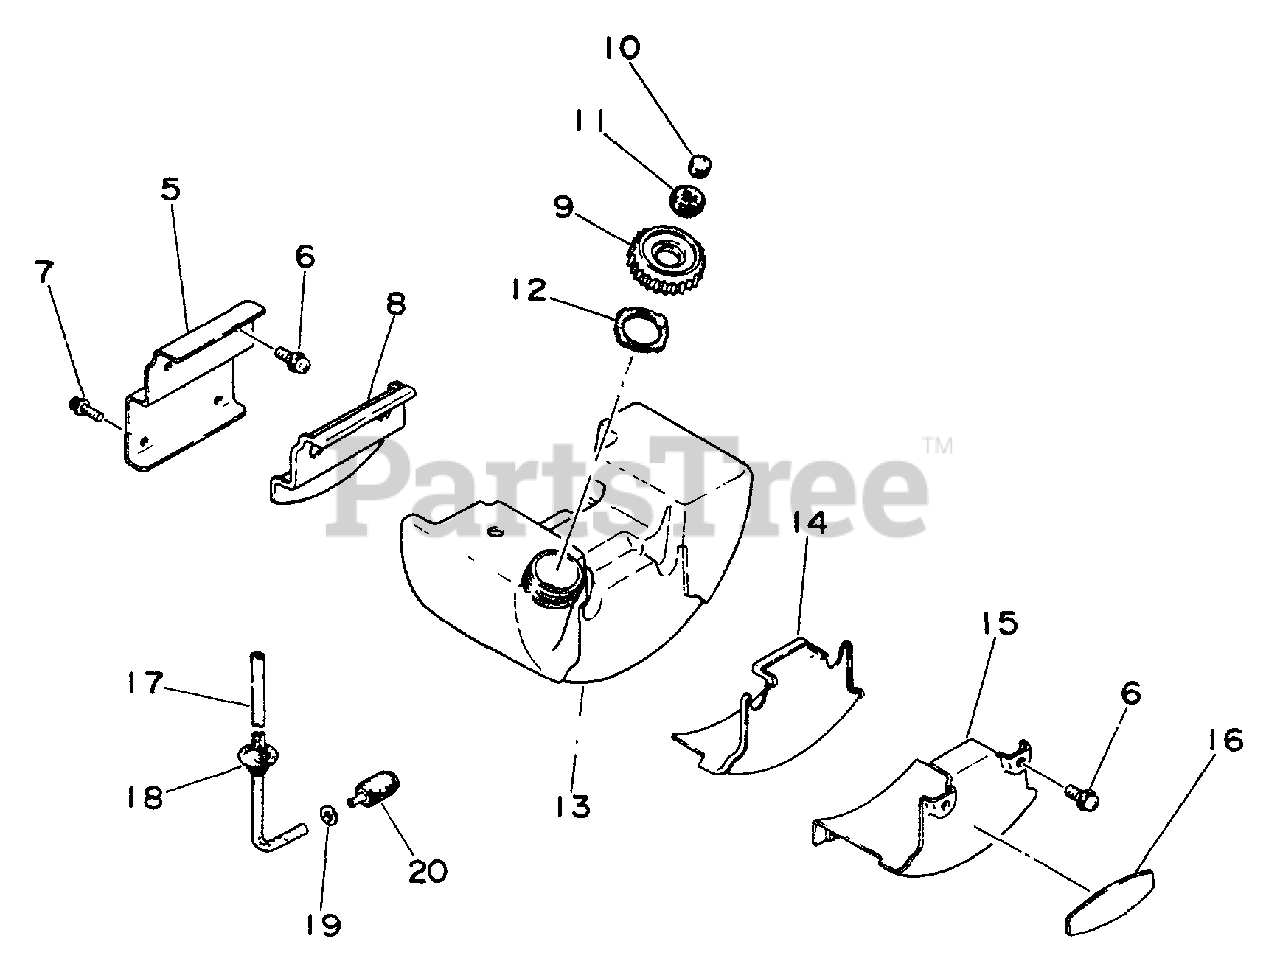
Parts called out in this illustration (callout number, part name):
5	BRACKET, FUEL TANK
6	SCREW 5×14
7	SCREW 4×14
8	CUSHION
9	CAP ASSY
10	FILTER, CHECK VALVE
11	VENT ASSY
13	TANK, FUEL
15	BRACKET, FUEL TANK
16	LABEL - ECHO
17	FUEL PIPE KIT
19	WASHER 5.5×12×0.8
20	FILTER, FUEL
